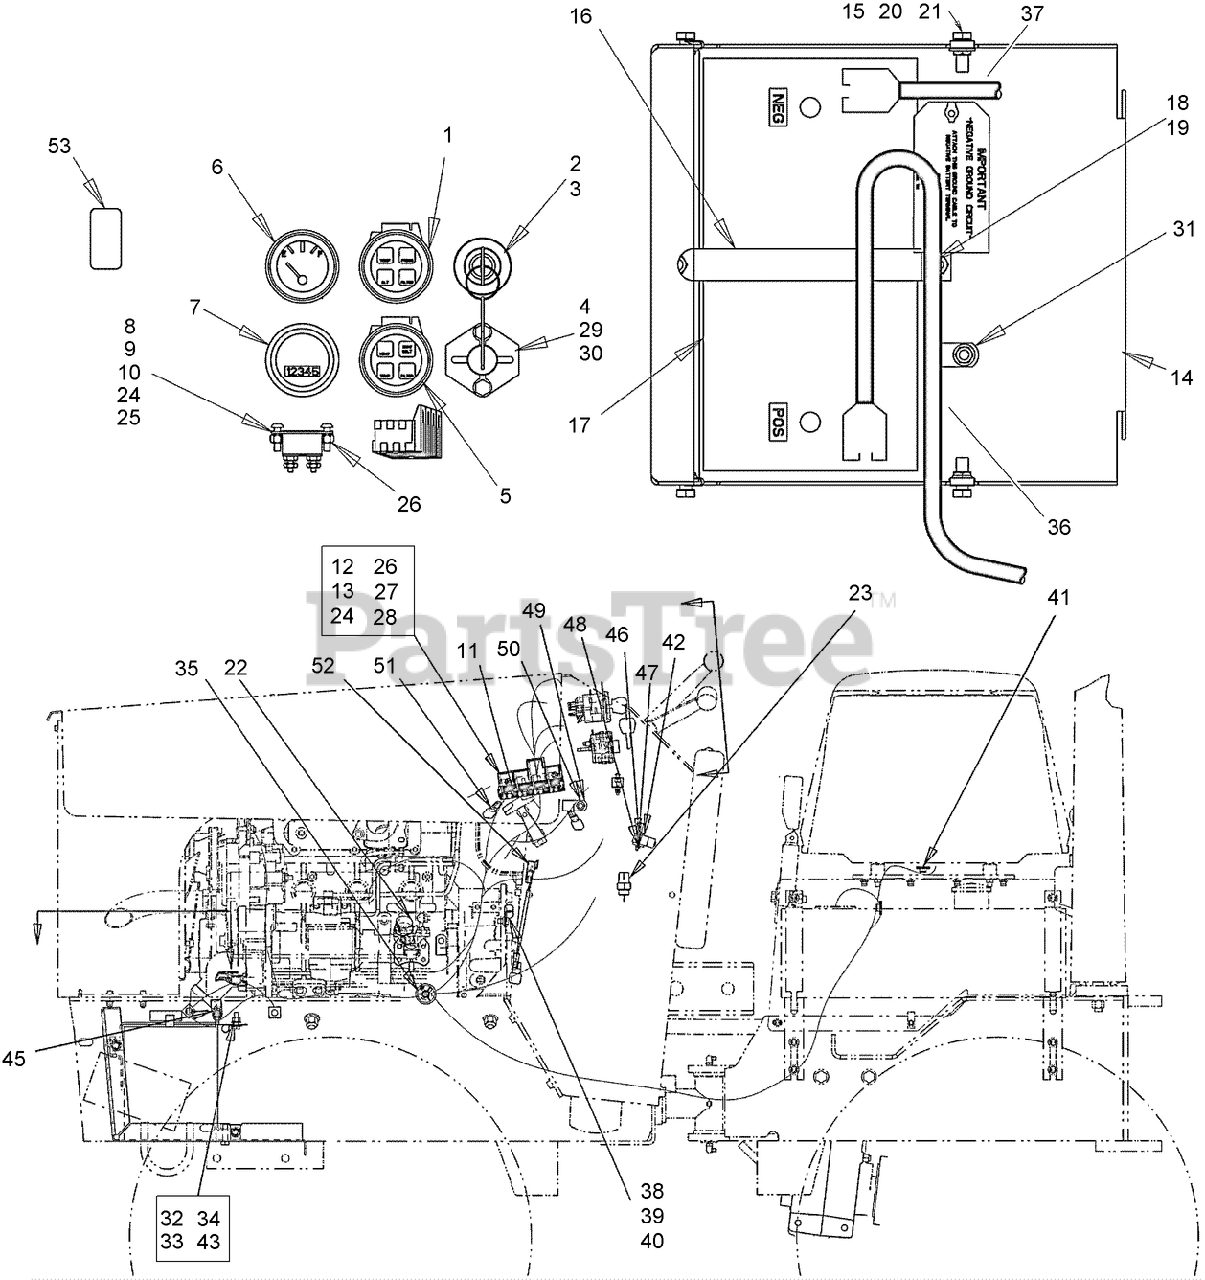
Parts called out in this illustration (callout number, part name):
1	GAUGE - Warning
2	ASSEMBLY - Ignition Switch
3	WASHER-FLAT
4	SWITCH-STARTER
5	CLUSTER - Hyd w/Neutral Indicator
6	GAUGE - Fuel
7	GAUGE - Hour
8	BREAKER - Circuit, 25 Amp
9	WASHER - Ext Tooth Lock 0.190 in ZND
10	NUT - Hex, #10-32 UNF, 303 Stainless Steel
11	HARNESS - Main
12	RELAY-Power
13	RELAY - Sealed Time Delay
14	TRAY - Battery
15	NUT-SPRING
16	BRACKET - Battery Hold-Down
17	BATTERY - 12 Volt (order from local Exide supplier)
18	BOLT
19	NUT-HEX
20	SCREW-HH
21	WASHER-FLAT
22	SWITCH-PRESSURE, VACUUM
23	SENDER - Temperature, Reservoir Oil Warning
24	SCREW - Machine, 10 - 32 x 3/4 Slotted Pan Head
25	WASHER - Spring Lock, Split Type, No. 10
26	NUT - Prev Trq #10 GR8 ZND Insert
27	WASHER - 0.203 x 0.469 x 0.049 in CST ZND
28	INSERT - 10-32 Short Well Nut
30	NUT-Prev Trq 1/4 GRC PHC Direct
31	CLAMP - Insul, 12.7mm 3/8 in Bolt ZND
32	SCREW-HH
33	WASHER-FLAT
34	NUT-HEX
35	SWITCH - Pressure, NO, Screw Terminal, Internal Ground
36	CABLE - Battery, Positive
37	CABLE - Battery, Negative
39	BOLT - Thd to Hd, M8 x 14 CL8.8 PHC
40	WASHER - Spring Lock Reg 8mm ZND.
41	CLIP - Wire Harness
42	SWITCH-NEUTRAL START
43	TAG - Important, Negative Ground Circuit
45	WASHER - External Tooth Lock, 5/16 ZND
46	BOLT-U, SWITCH MTG (H435814)
47	SPACER-SWITCH
48	NUT - KEPS Ext T Wshr #6 - 32 UNC ZP
49	CLAMP-Insul 19.0 mm 3/8 in Bolt ZND
50	SCREW-HH
51	DIODE - Isolation
52	HARNESS - Whitaker X Deutsch
53	BLANK-SWITCH, ROCKER
